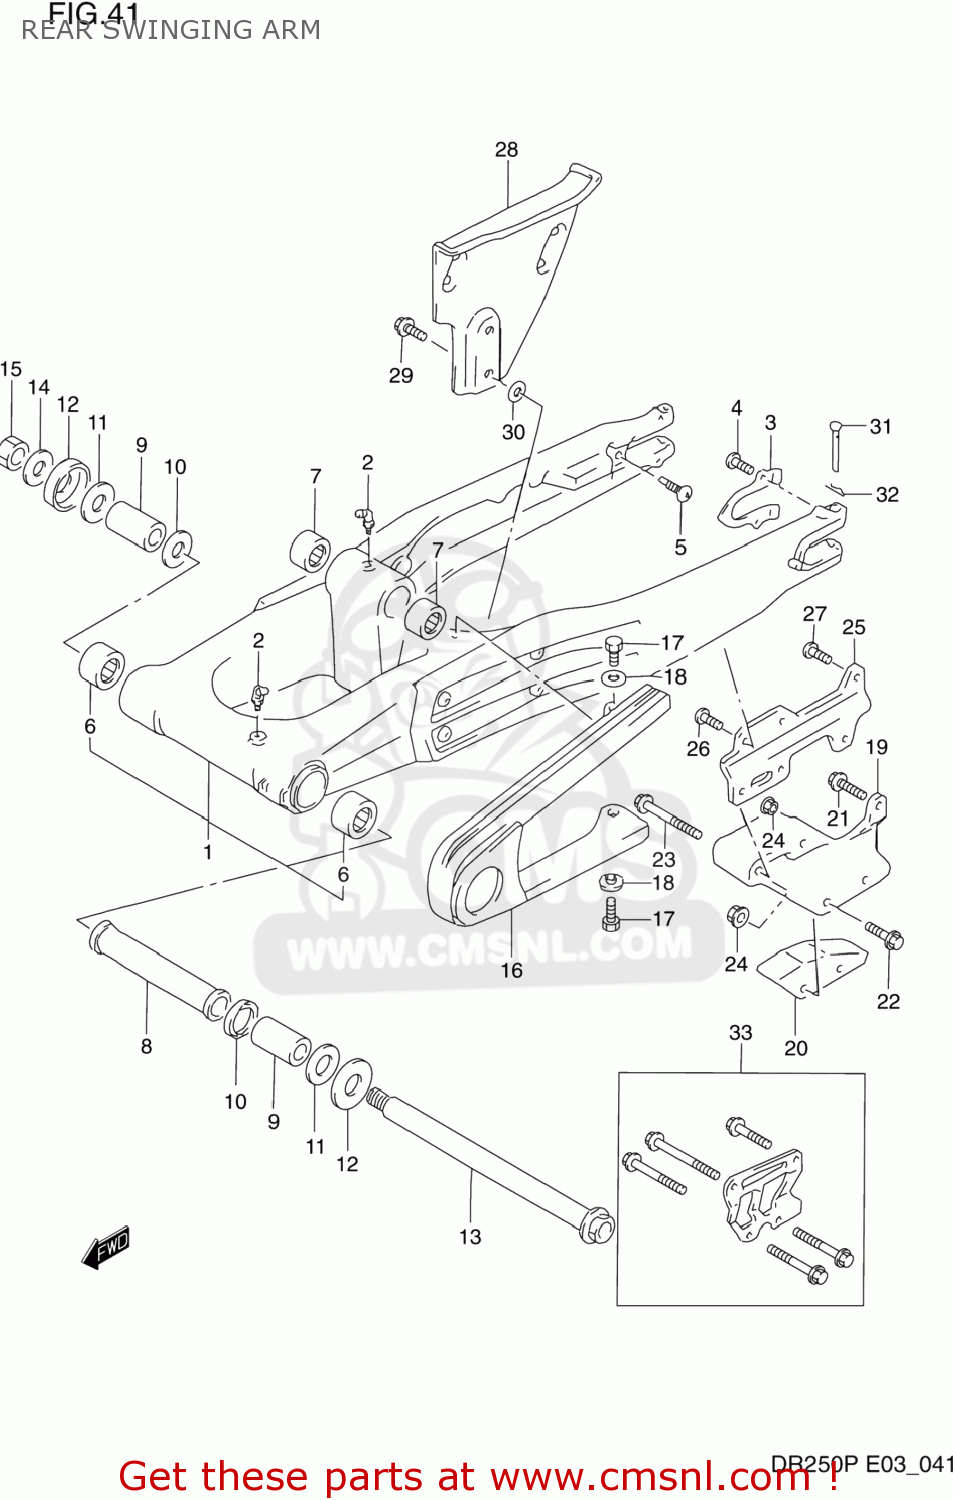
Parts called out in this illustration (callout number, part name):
1	SWING ARM ASSEMBLY,REAR
2	NIPPLE,GREASE
3	PLATE,SWING ARM RR
4	SCREW (5X8)
5	SCREW (M10X21)
6	BEARING(22X29X30)
7	BEARING(20X27X23.5)
8	SPACER,SWING ARM PIVOT,CENTER
9	SPACER,SWGARM PIVOT BRG
10	SEAL,OIL(22X29X4)
11	WASHER
12	COVER,SWINGINGARM PIVOT
13	SHAFT,SWINGING ARM PIVOT
14	WASHER
15	NUT
16	BUFFER,CHAIN TOUCH DEFENSE
17	BOLT
18	WASHER
19	GUIDE,CHAIN
20	DEFENSE,CHAIN GUIDE
21	BOLT 6X25
22	BOLT,UNDER
23	BOLT
24	NUT
25	BRACKET,CHAIN GUIDE
26	SCREW
27	BOLT
28	GUARD,CHAIN
29	BOLT
30	WASHER
31	PIN
32	CLIP
33	PLATE SET,CHAIN GUIDE
